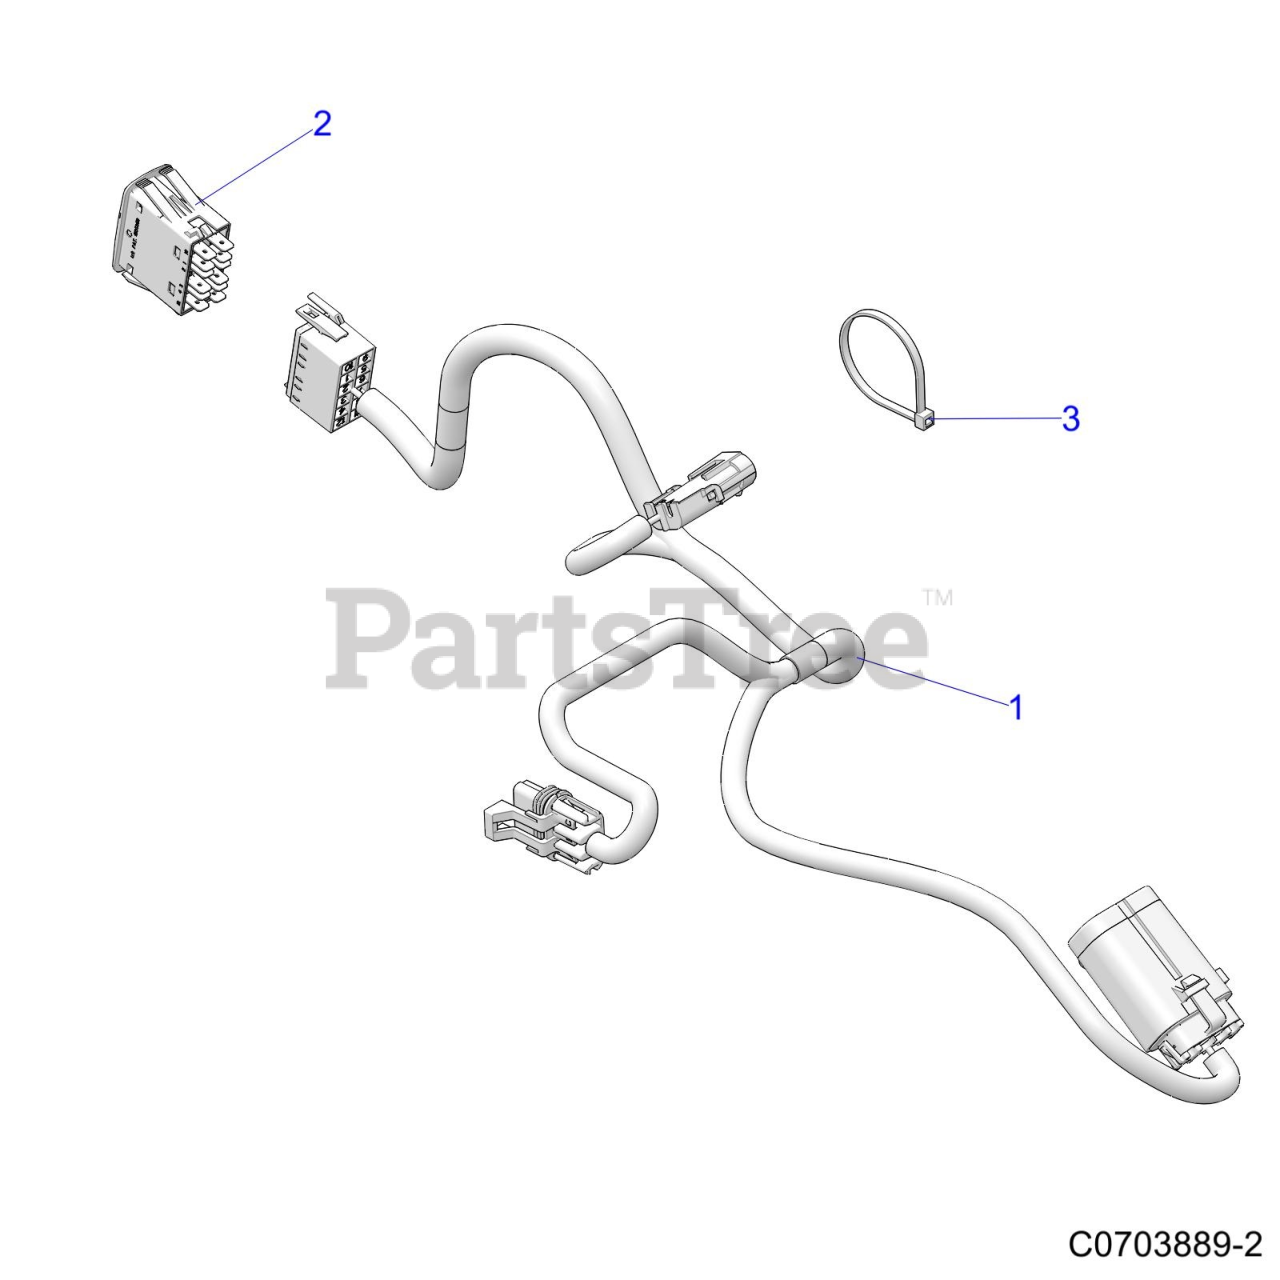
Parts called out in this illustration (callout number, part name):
1	HARNESS-BOX LIFT,ZS
2	SWITCH-BOX LIFT
3	CABLE TIE (10)
